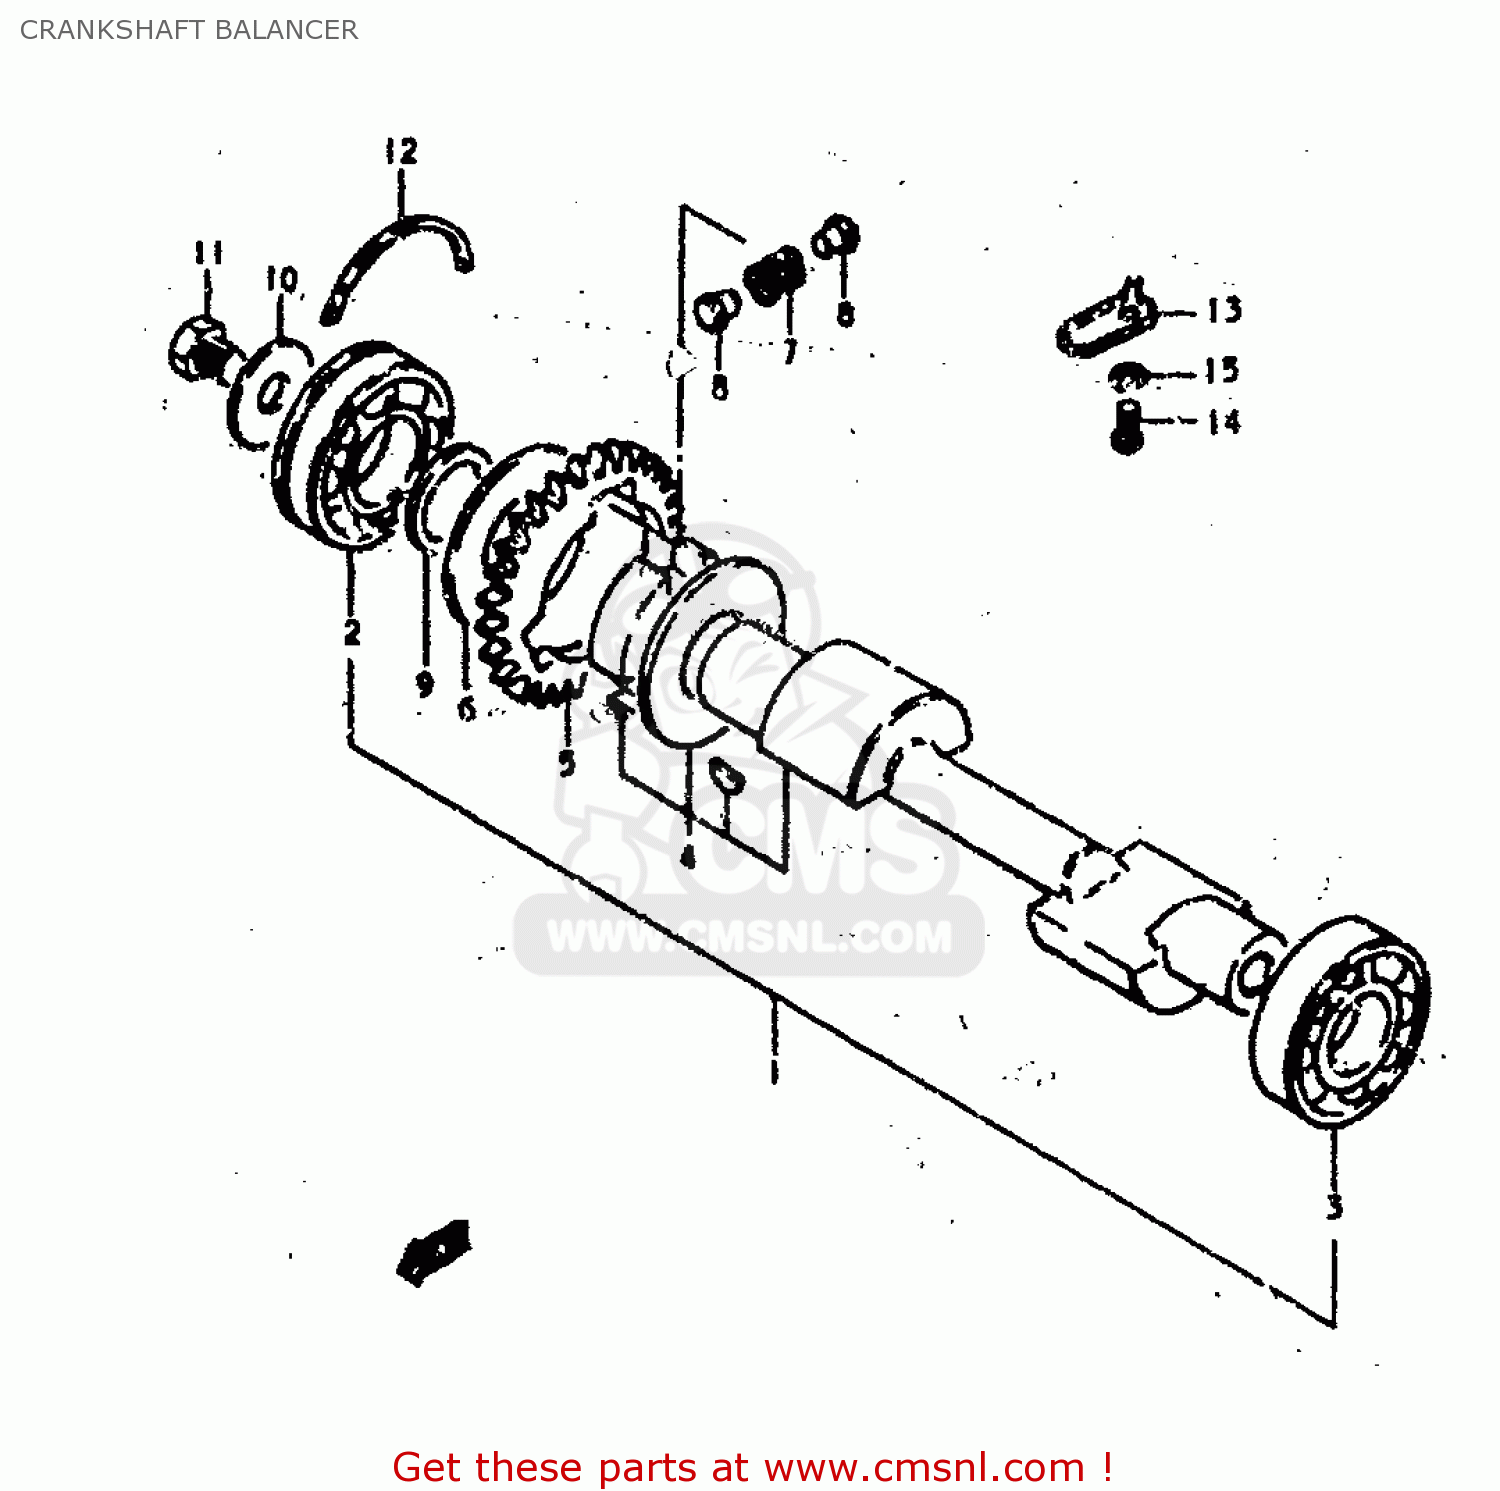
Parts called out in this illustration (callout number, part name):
1	BALANCER,CRANKSHAFT
2	BEARING
3	BEARING
4	CLUTCH SET,STARTER
5	GEAR,CRANK BALANCER DRIVE
6	WASHER (31X70X3)
7	SPRING
8	PIN
9	WASHER
10	WASHER
11	BOLT ,12X16
12	C-RING
13	PLATE, OIL RESERVE
14	SCREW
15	LOCK WASHER
